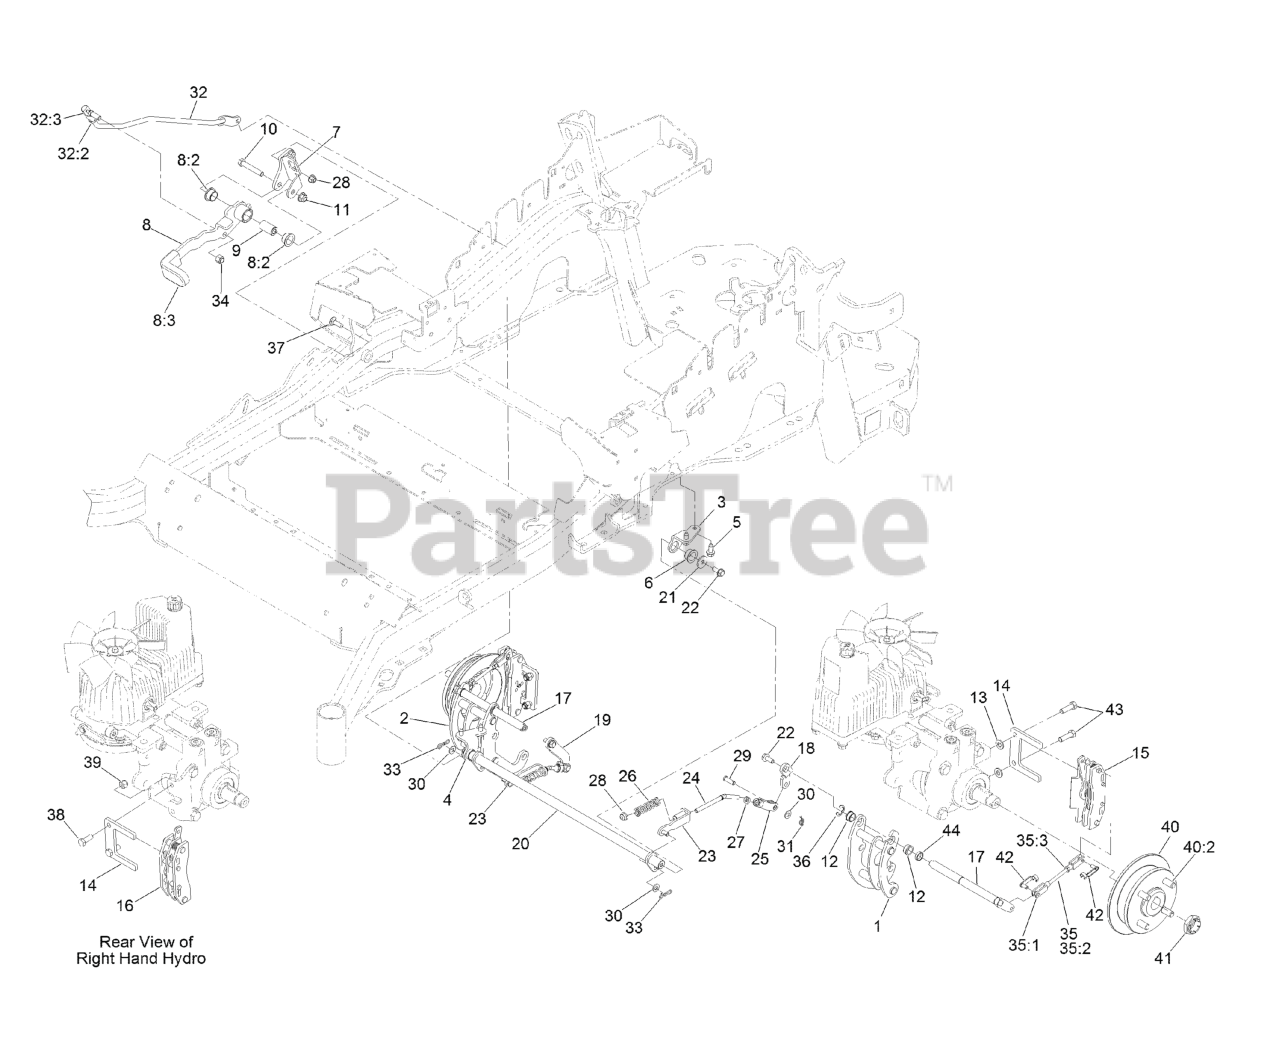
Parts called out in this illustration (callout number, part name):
1	MOUNT-BELLCRANK, LH
2	MOUNT-BELLCRANK, RH
3	MOUNT-PIVOT, LH
4	MOUNT-PIVOT, RH
5	Screw-HWH 5/16-18 X 3/4 Tf
6	BUSHING-FLANGE
7	BRACKET-MOUNT
8	BRAKE LEVER ASM W/ GRIP
8:2	BUSHING-FLANGE
8:3	GRIP-LEVER
9	HANDLE-PIVOT, BRAKE
10	SCREW-HH
11	NUT-HF, NI
12	BUSHING
13	WASHER-FLAT
14	PLATE-MOUNT, BRAKE
15	CALIPER-BRAKE
16	CALIPER-BRAKE, RH
17	BELLCRANK
18	ARM-INNER, LH
19	ARM-INNER, RH
20	SHAFT-CROSS
21	WASHER-FLAT
22	SCREW-HHF
23	BRACKET-L
24	LINKAGE-MID
25	YOKE-OFFSET
26	SPRING-COMPRESSION
27	NUT-JAM
28	NUT-HF, NI
29	PIN-CLEVIS
30	WASHER-PLAIN
31	PIN-COTTER, LOCKING
32	FRONT LINKAGE ASM
32:2	END-TIE ROD, RH
32:3	NUT-HJ
33	PIN-COTTER, LOCKING
34	NUT-LOCK
35	REAR LINKAGE ASM
35:3	NUT-JAM
37	BOLT-CARR
38	SCREW-HH
39	NUT-LOCK, NI
40	WHEEL HUB ASM
40:2	STUD-WHEEL
41	LOCKNUT
42	PIN-CLEVIS, SPRING
43	SCREW-LOCK, PATCH
